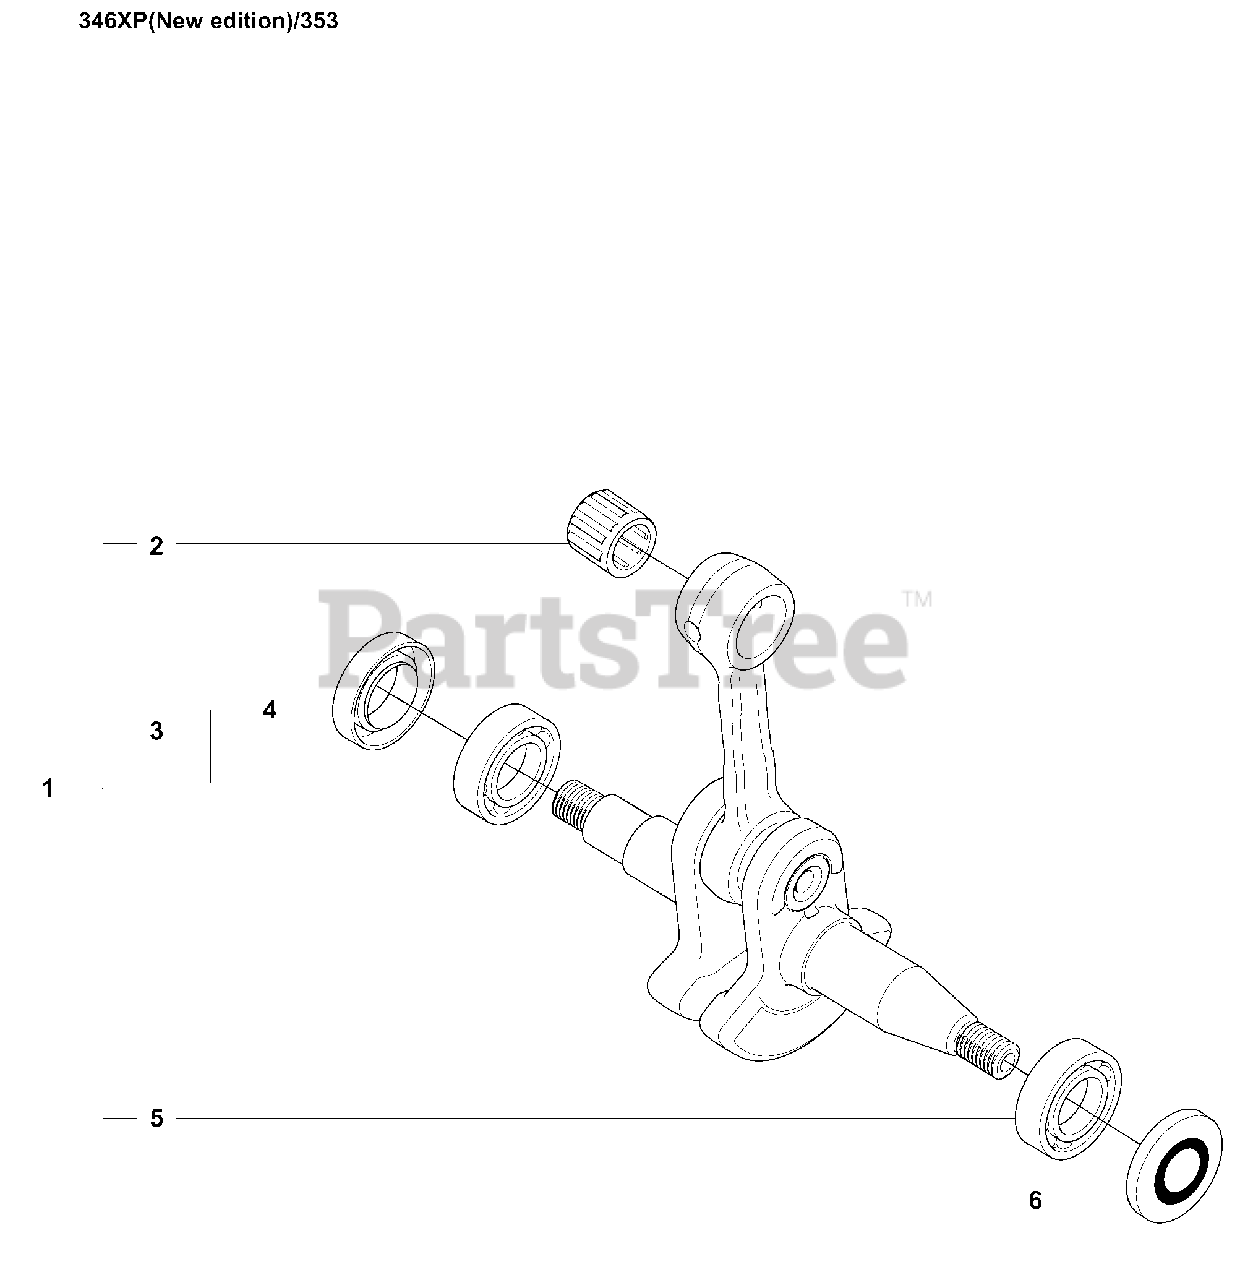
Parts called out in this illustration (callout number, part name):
1	CRANKSHAFT
2	SUPPORT BUSHING
3	%BEARING W/SEAL
4	SEALING
5	BALL BEARING-6202-C3 SKF
